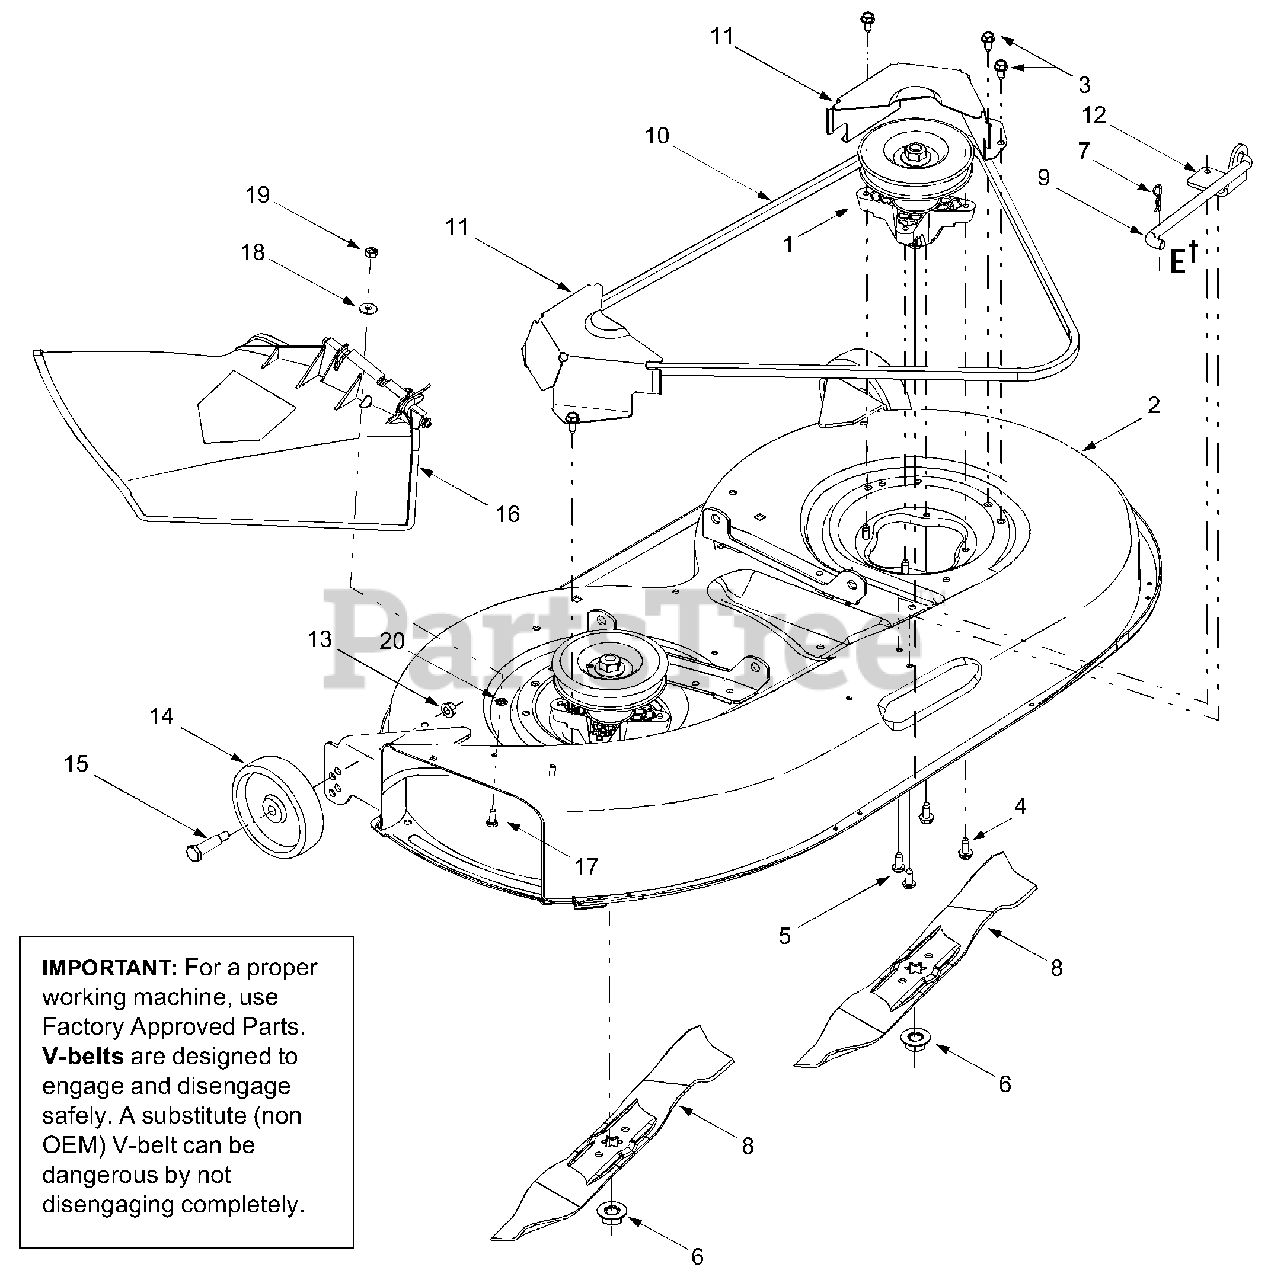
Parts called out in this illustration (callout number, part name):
1	Spindle Assembly
4	Screw, 5/16-18 x .75
5	Self-tapping Screw, 5/16-18 x .75
6	Hex Flange Nut, 5/8-18
7	Internal Cotter Pin, .080 x 1.56
8	Blade, 21.23" Star
9	Deck Hanger Link/Anti-sway Rod
10	Deck Belt
13	Flange Lock Nut, 3/8-16
14	Deck Wheel, 5 x 1.38
15	Shoulder Screw, .498 x 1.53
16	Discharge Chute Assembly
17	Hex Cap Screw:1/4-20 x .620
18	Bell Washer, .265 x .75 x .062
19	Hex Nut, 1/4-20
20	Push Nut, 1/4
